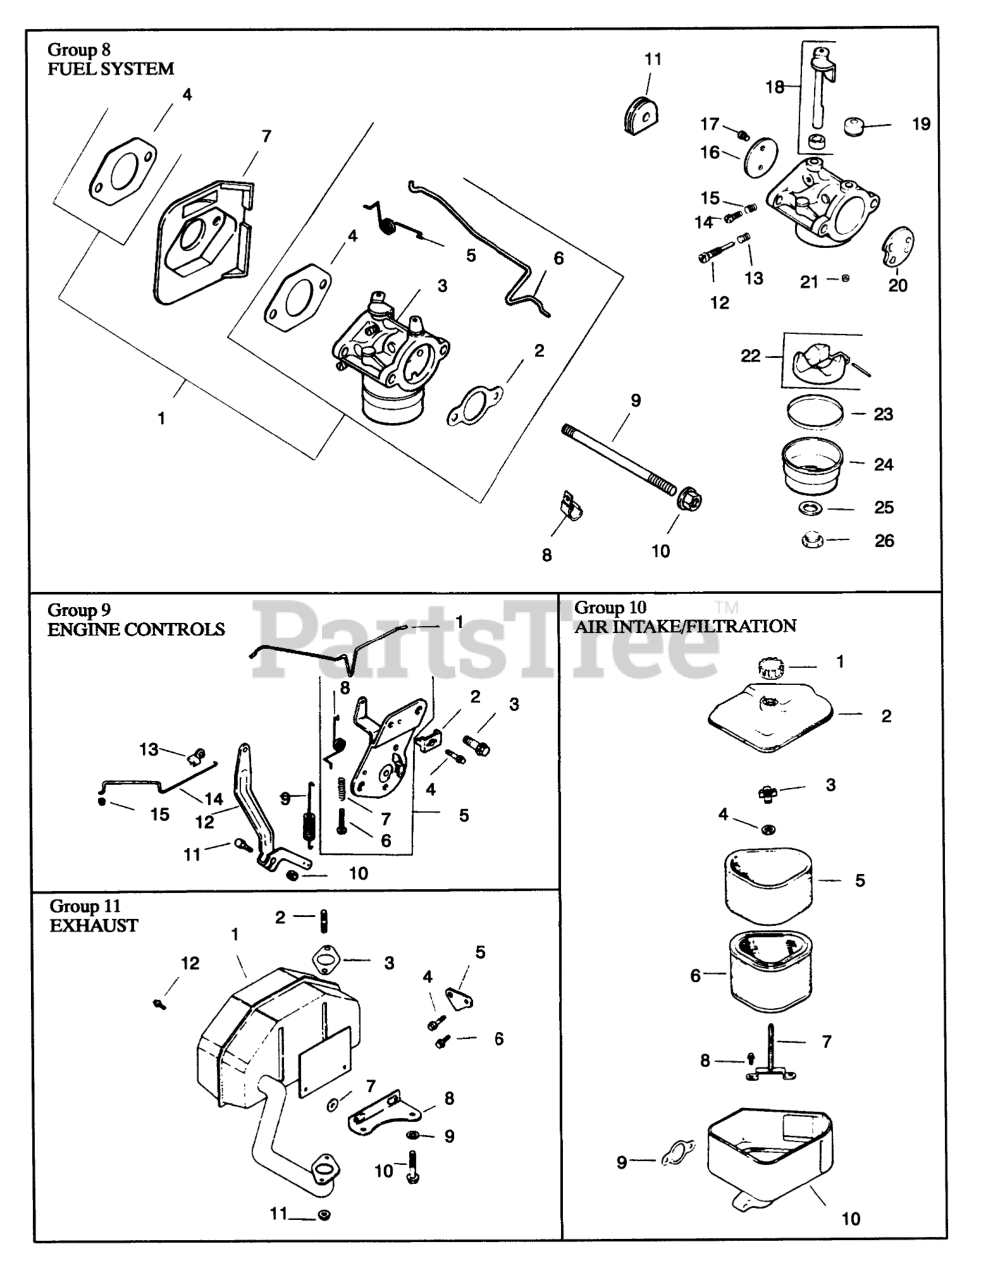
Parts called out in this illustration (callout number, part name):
1	Kit-Carburetor (Incl Ref. #2-6)
1	Linkage-Choke
1	Knob-Air Cleaner Cover
1	Muffler
2	Gasket-Air Cleaner
2	Cover-Air Cleaner
2	M-0829033 Stud-Exhaust Manifold
3	Carburetor Assembly (Incl Ref. #12-26)
3	Screw
3	Nut-Wing
3	Gasket-Exhaust
4	Gasket-Carburetor
4	Screw
4	Washer
4	SM-0645025 Screw-Lifting Strap
5	Spring-Choke
5	Control-Speed (incl. Ref. #6-8)
5	Precleaner-Element
5	Strap-Lifting
6	Linkage-Choke
6	Element-Air Cleaner
6	SM-0645020 Screw-Valve Cover
7	Deflector-Heat
7	Stud-Mounting Plate
7	X-25-52 Washer
8	Clip-Cable
8	Spring-Choke
8	Screw-Mounting Plate
8	Bracket-Muffler
9	Stud
9	Spring-Governor
9	Gasket-Air Cleaner
9	Washer-Flat
10	Base-Air Cleaner
10	Screw-Oil Pan
11	Grommet
11	Screw
11	M-0841080 Nut-Muffler
12	Needle-Idle
12	Lever-Governor
12	M-0650012 Screw-Muffler
13	Spring-Idle
13	Bushing
14	Screw-Idle
14	Linkage-Throttle
15	Spring-Idle
15	Bushing-Linkage Retaining
16	Plate-Throttle
18	Shaft Assembly-Throttle
19	Cap-Choke Lever
20	Plate-Choke
21	Jet-Main
22	Kit-Float
23	Gasket-Bowl
24	Bowl-Fuel
25	Gasket-Bowl
26	Screw-Bowl
